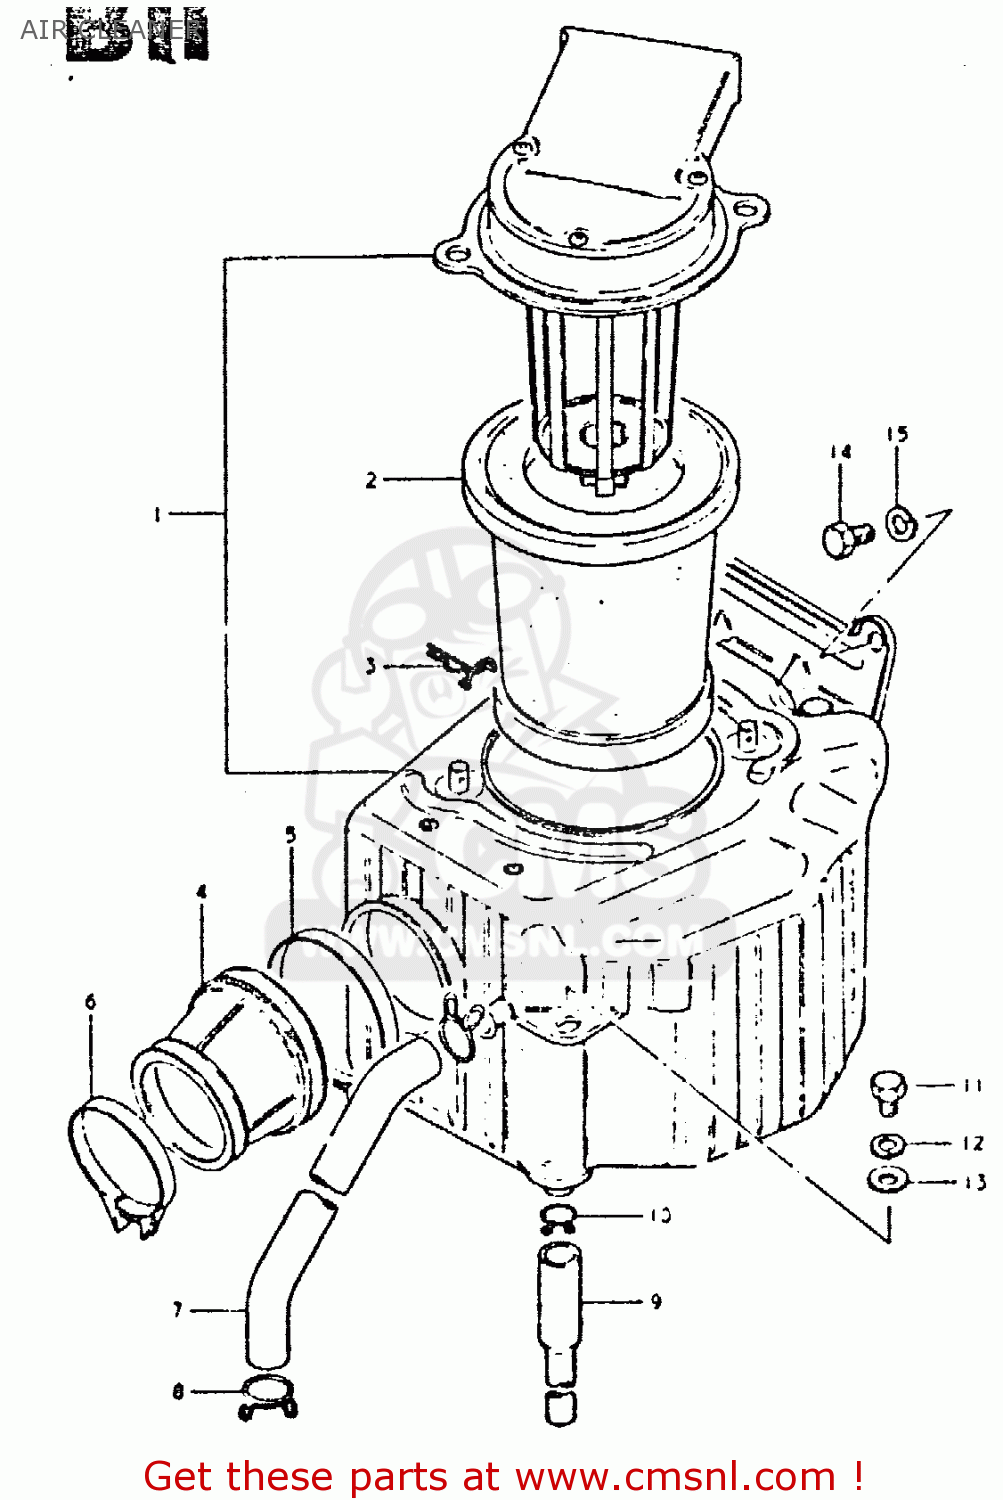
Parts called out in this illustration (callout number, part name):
1	CLEANER ASSY, AIR
2	FILTER
3	SNAP PIN,AIR CLEANER
4	TUBE,AIR CLEANER OUTLET
5	CLAMP
6	CLAMP
7	TUBE,BREATHER
8	CLIP,BREATHER TUBE
9	DRAIN TUBE
10	CLIP
11	BOLT, UPPER
12	LOCK WASHER
13	WASHER 6MM
14	BOLT
15	LOCK WASHER
